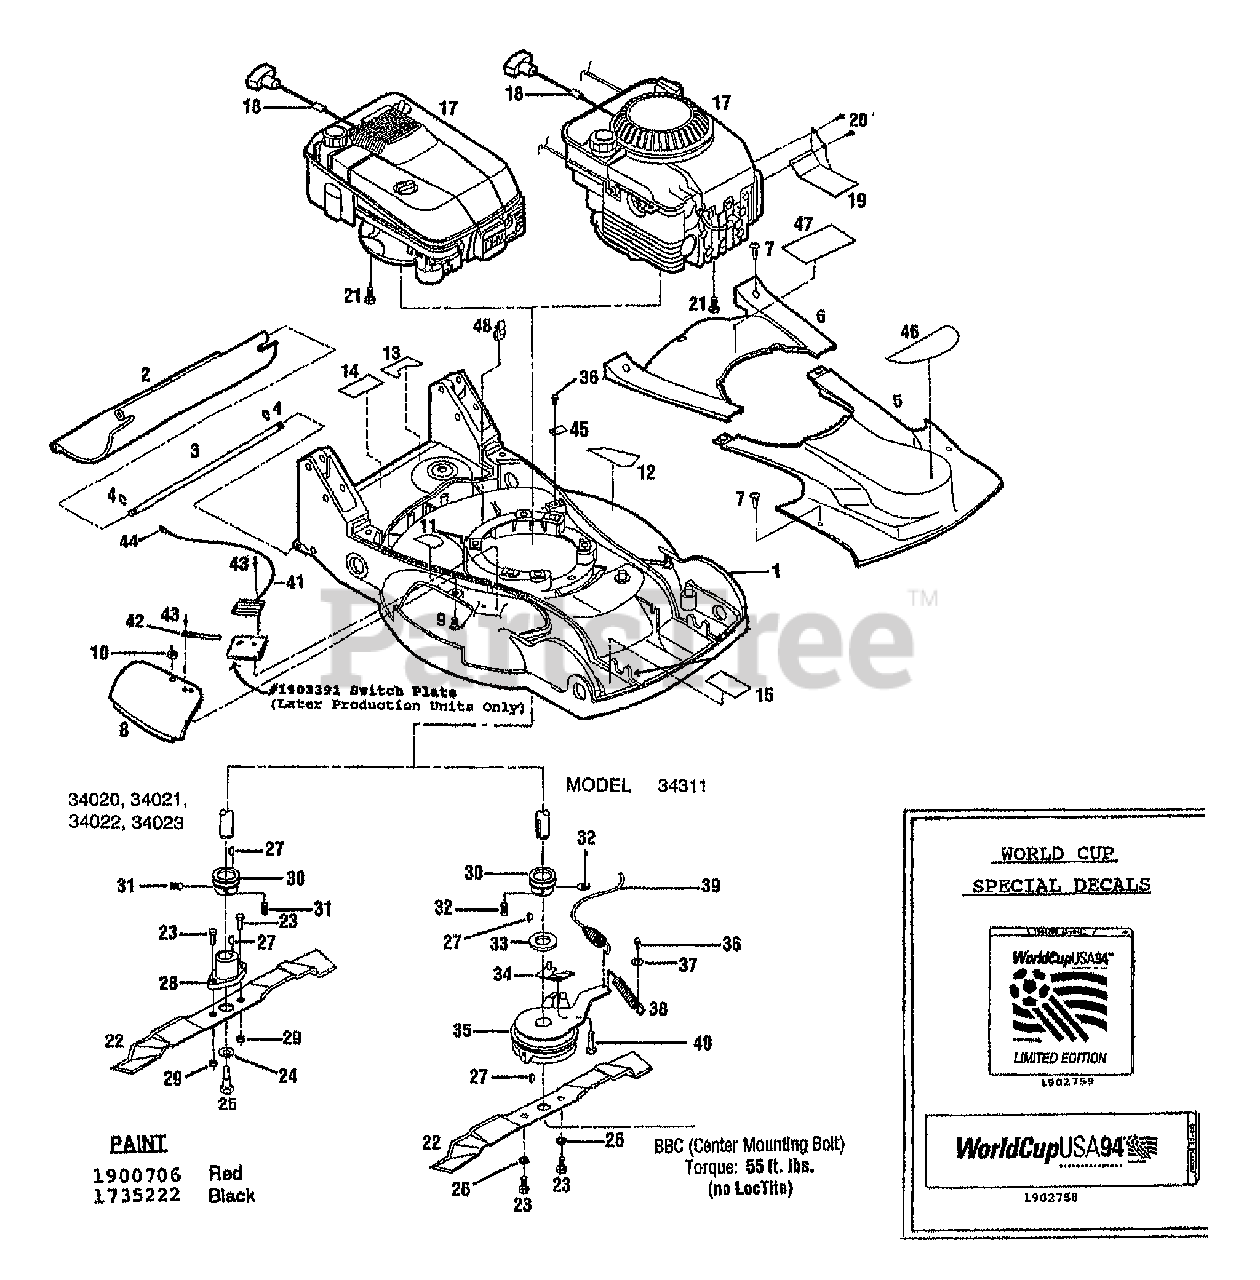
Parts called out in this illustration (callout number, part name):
1	MOWER DECK (INCL. 2-4,9,11-12,14-15,41 & 43)
2	FLAP-SAFETY WITH NOTCH
3	ROD-FLAP
4	RING-RET. "E".312 ID
5	COVER-FRONT W/DECAL T/B
6	COVER-REAR W/DECAL T/B
7	SCR-PH M12-24X.63 THFRM ZP
8	DOOR-DISCHARGE W/TAB
9	KIT-DECK STUD REPLACE
10	NUT-HT/LK 5/16-24
11	DECAL-DANGER USE GUARD
12	DECAL-OPEI CAUTION
13	DECAL-CUTTING HEIGHT
14	DECAL-WARNING THROWN OBJECT
15	DECAL-CAUTION PINCH POINT {NOT 34020}
17	ENGINE, 4HP B&S #122702-3182 RECOIL START ( MODELS 34020 & 34021)
17	ENGINE, 5HP B&S #124802-3433 RECOIL START ( MODEL 34022)
17	ENGINE, 5HP B&S #124807-3435 ELECTRIC START (MODEL 34023)
17	ENGINE, 5.5HP B&S #09977200628 EUROPA, RECOIL START, OHV (34311 & 34313)
18	STOP-STARTER ROPE
19	SHIELD-HEAT PNT {NOT 34311, 34313}
20	SCR-SELF TAP
21	SCR-HH 3/8-16X1.25 THDFRM
22	KIT-BLADE 21" MULCH MOWER {34020,34021, 34022,34023}
22	BLADE-MULCHER 21" {34020,34021,34022,34023}
22	KIT-BLADE 21" BBC MULCH MOWER {34311,34313}
22	BLADE-MULCHER 21" BBC {34311,34313}
23	SCR-HH 3/8-16X1.0 G5 ZP {NOT 34311,34313}
23	SCR-HH M10X1.5X30MM {34311,34313}
24	WASHER-LK .5 {NOT 34311,34313}
25	SCR-SHLDR 3/8-24X1.63 {NOT 34311,34313}
26	WASHER-LK M10.2 {34311,34313}
27	KEY-WOODRUFF {34020,34021,34022,34023}
27	KEY-WOODRUFF .156X.625 {34311,34313}
28	COUPLING-BLADE {NOT 34311,34313}
29	NUT-LOCK 3/8-16 {NOT 34311,34313}
30	SHEAVE-ENGINE {NOT 34020,34311,34313}
30	SHEAVE-ENGINE {34311,34313}
31	SCR-SQHD 1/4-20X1/2 GR5 {NOT 34020,34311, 34313}
32	SCR-SET 1/4-20 {34311,34313}
33	WASHER-FLAT 3/8 SAE {34311,34313}
34	BRKT-LOCATING ZP {34311,34313}
35	CLUTCH-TYPE 6 BBC {34311,34313}
36	SCR-HW M10-24 THRFRM {34311,34313}
37	WASHER-M12 {34311,34313}
38	SPRING-EXTENSION {34311,34313}
39	CABLE, BLADE BRAKE CONTROL - SEE GRID C-10 ( MODELS 34311 & 34313)
40	SCR-SHLDR 5/16-18X2.00 {34311,34313}
41	SWITCH-IGNITION GROUND
42	TAB-SWITCH
43	RIVET-POPOP
44	SCR-HH 10-24X.25 THRD FRM
45	CLAMP-CABLE {34311,34313}
46	DECAL-LOGO MULCHER T/B
47	DECAL-WARNING SAFETY LIST
48	CLIP-SPECIAL {34021,34022,34023}
